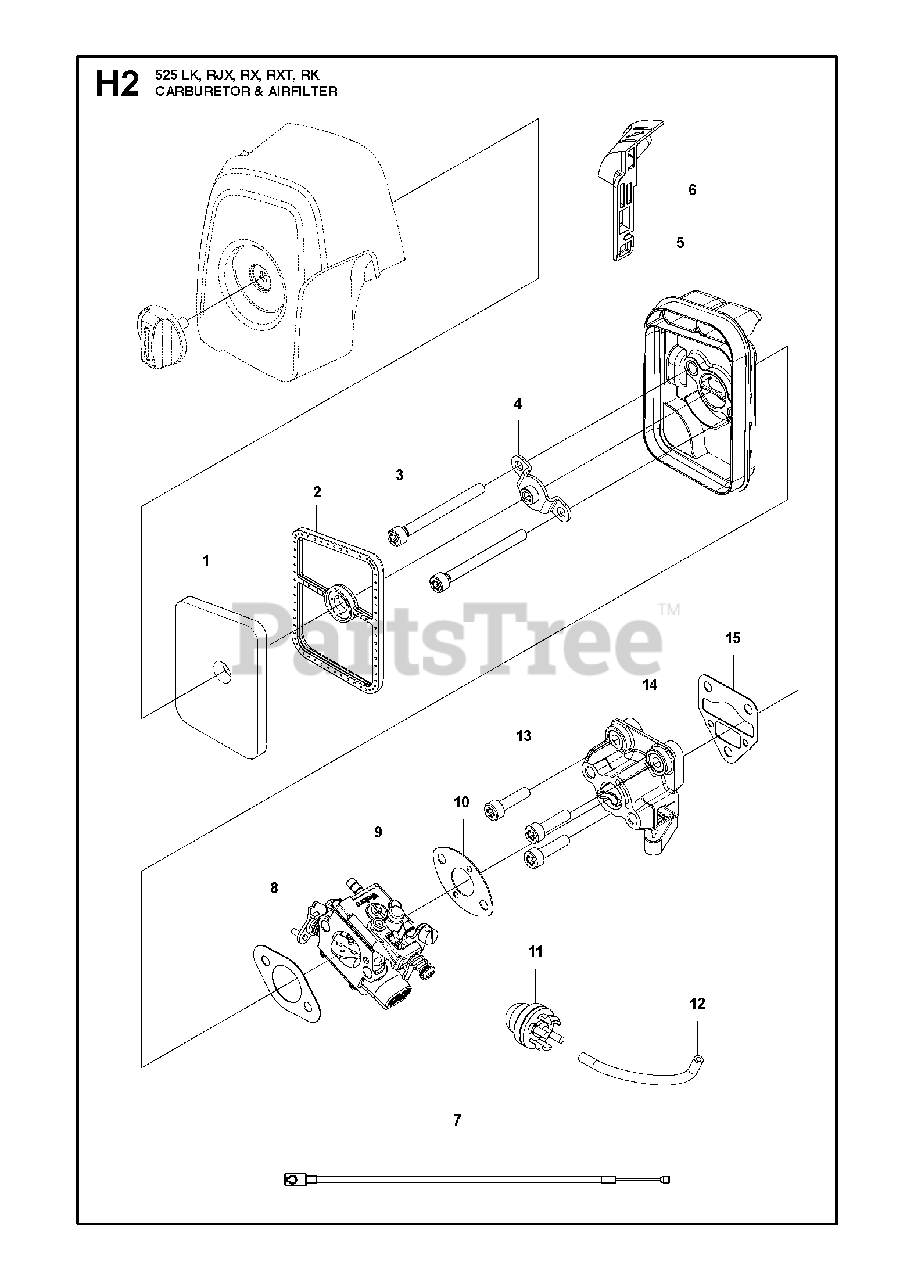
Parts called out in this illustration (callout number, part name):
1	AIR FILTER
2	AIR FILTER FELT
5	FILTER HOUSING
6	CHOKE CONTROL
7	THROTTLE CABLE
9	CARBURETTOR ASSY
10	GASKET CARBURETOR
11	AIR PURGE BUBBLE
13	BOLT
